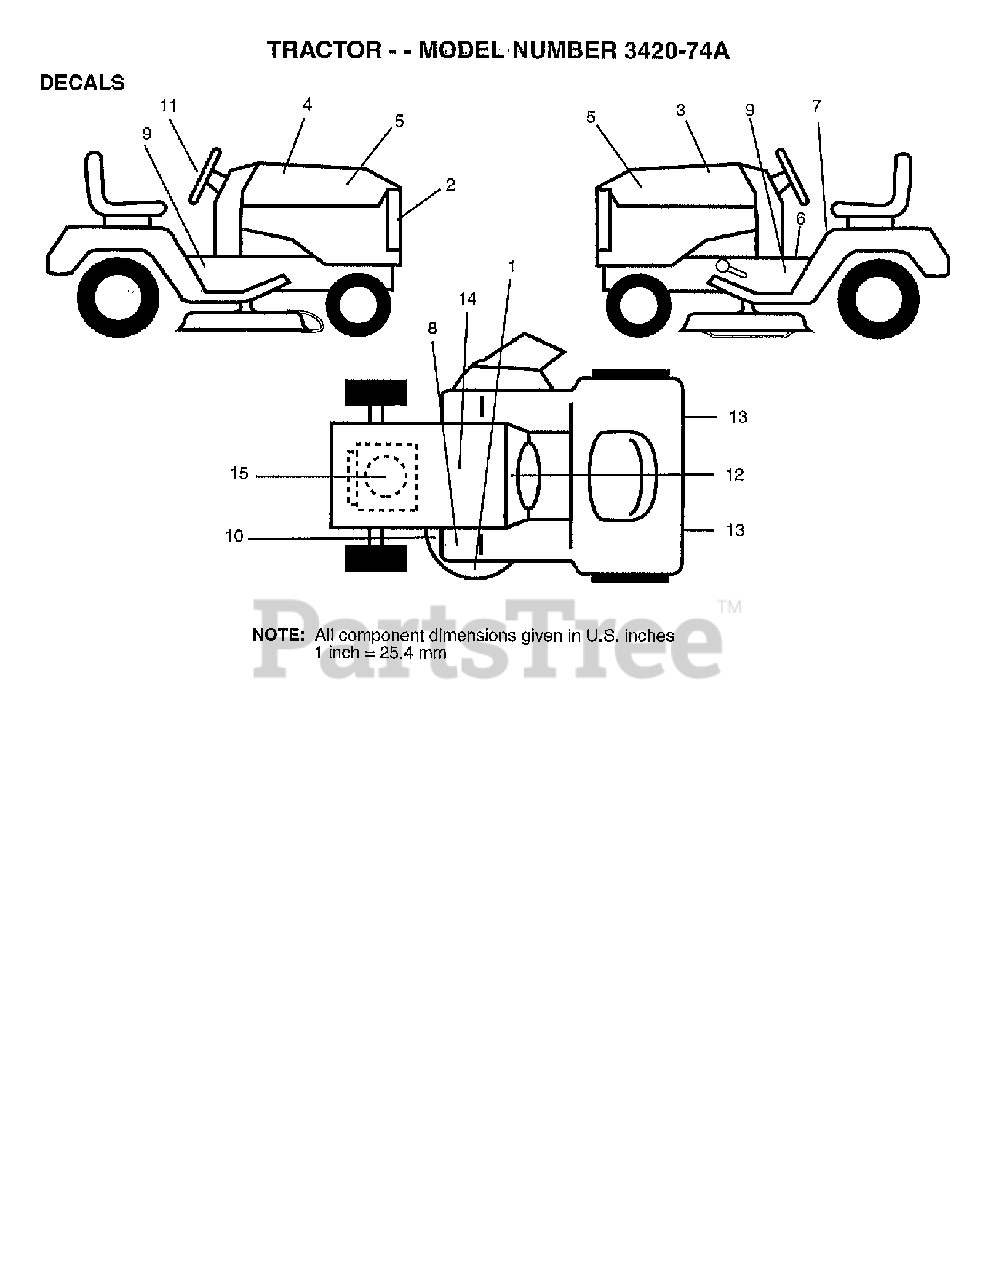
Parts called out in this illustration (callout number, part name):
2	Poulan TBD
3	Poulan TBD
4	Poulan TBD
5	Poulan TBD
6	DECAL PARK BRAKE
9	Poulan TBD
10	DECAL V-BELT SCHEMATIC
11	Poulan TBD
13	REFLECTOR-TAIL YT
14	Poulan TBD
15	Poulan TBD
